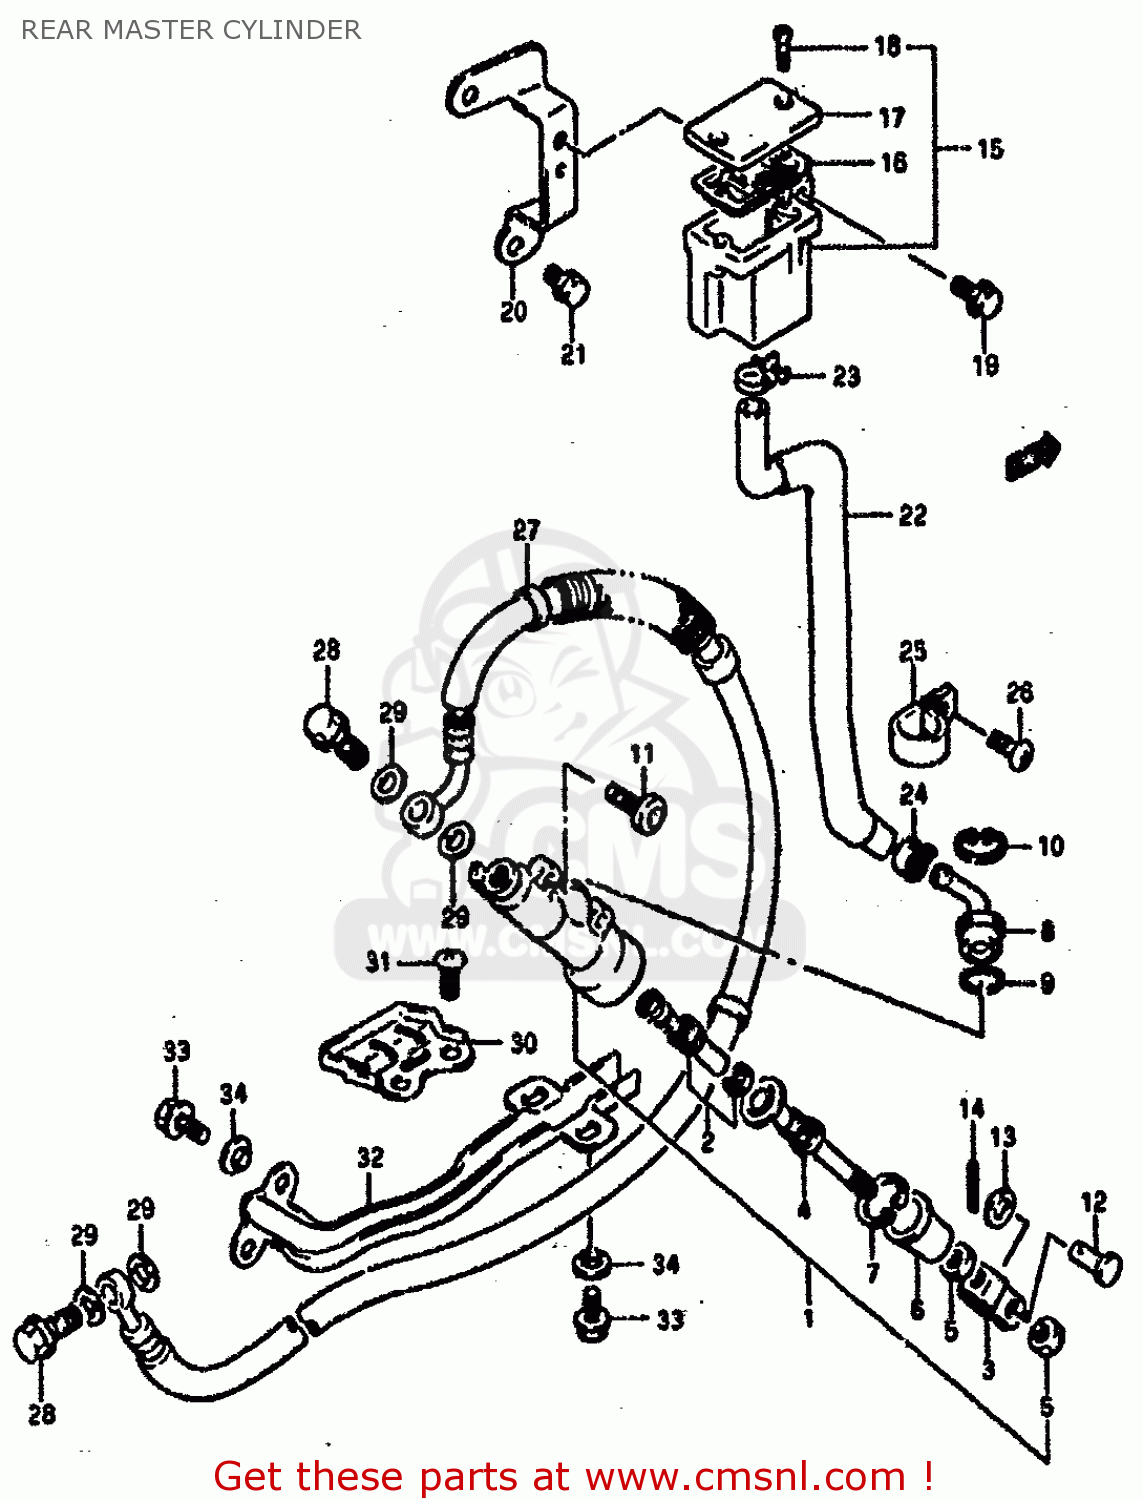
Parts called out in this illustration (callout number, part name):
1	CYLINDER ASSY,REAR MASTER
2	PISTON/CUP SET
3	YOKE
4	ROD,PUSH
5	NUT
6	BOOT
7	CIRCLIP
8	CONNECTOR
9	O RING
10	CIRCLIP
11	BOLT(6X18)
12	PIN(8X20)
13	WASHER(8.5X13X1.6)
14	PIN
15	TANK ASSEMBLY,RESERVOIR
16	DIAPHRAGM
17	CAP
18	SCREW
19	BOLT 6X16
20	PLATE,RESERVOIR TANK
21	BOLT(6X8)
22	HOSE,RESERVOIR TANK
23	CLAMP
24	CLAMP
25	CLAMP,HOSE GUIDE
26	SCREW
27	HOSE,REAR BRAKE
28	BOLT UNION
29	WASHER(10X15X1.5)
30	GUIDE,BRAKE HOSE (SILVER)
31	SCREW
32	PROTECTOR, BRAKE HOSE
33	BOLT
34	WASHER
